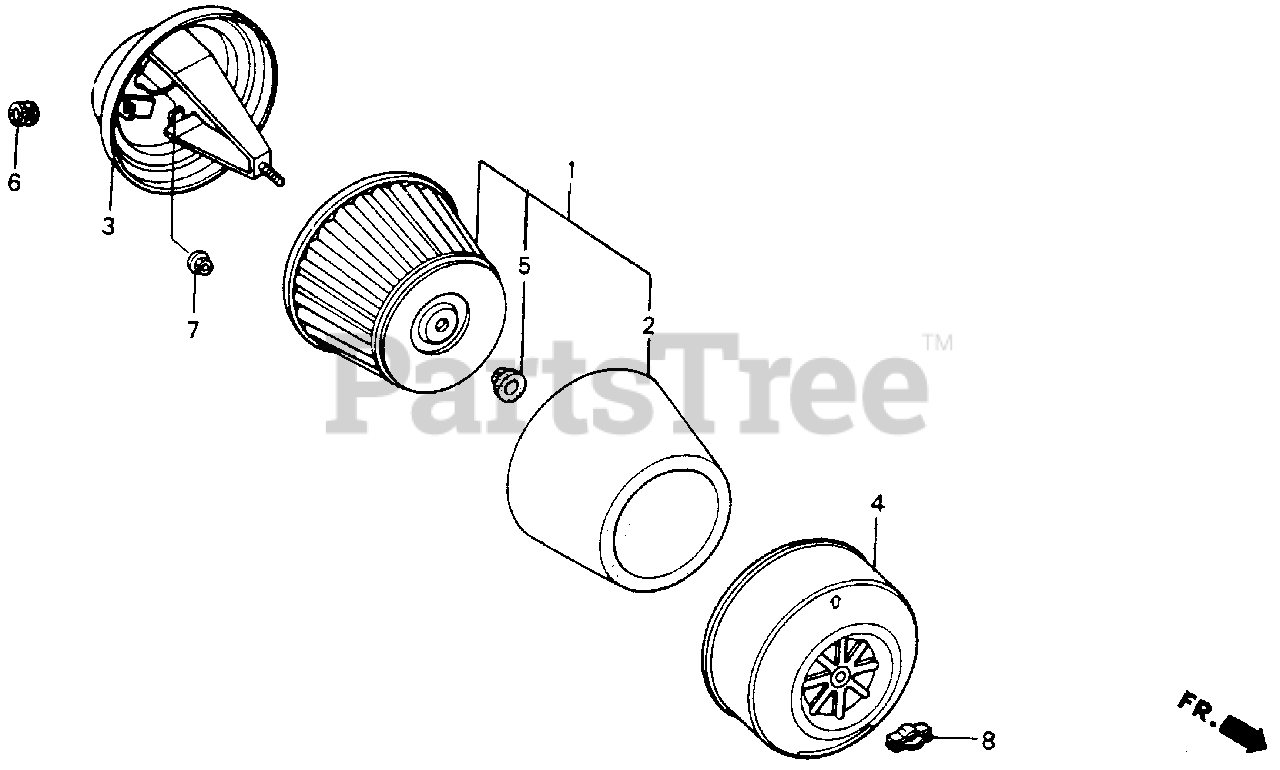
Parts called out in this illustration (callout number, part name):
1	ELEMENT, AIR CLEANER
2	FILTER (OUTER)
3	HOUSING, AIR CLEANER
4	COVER, AIR CLEANER
5	GROMMET, AIR CLEANER
6	GROMMET, FENDER
7	NUT, CAP (6MM)
7	NUT, FLANGE (6MM)
8	WINGNUT, AIR CLEANER COVER
